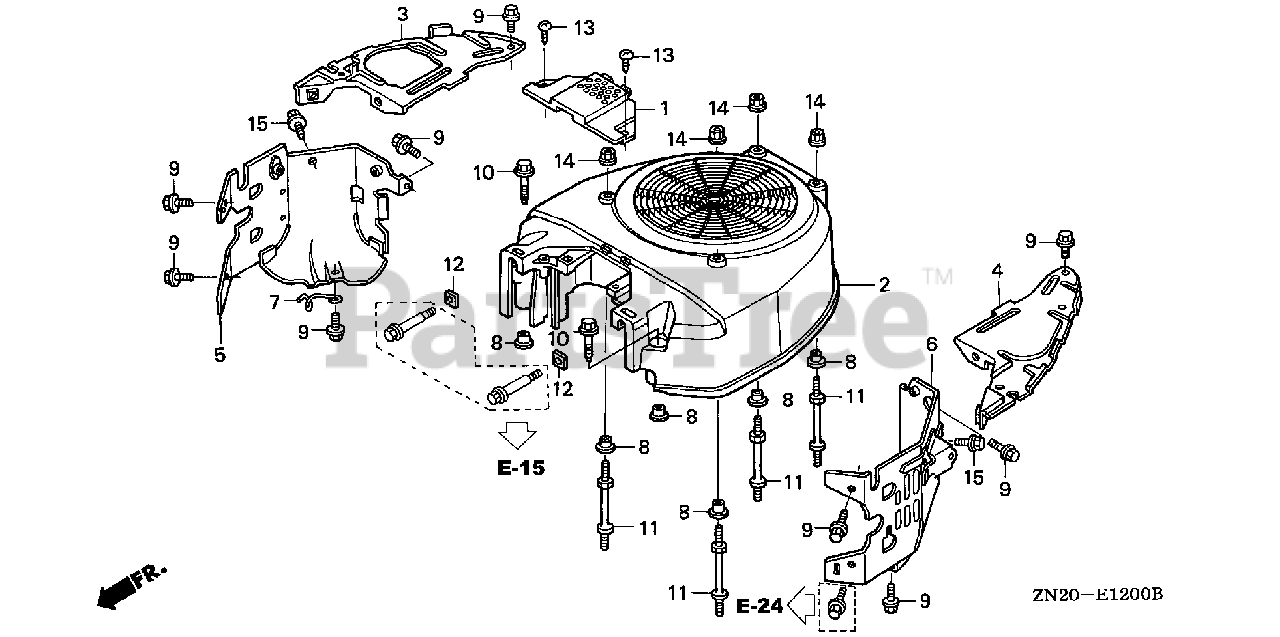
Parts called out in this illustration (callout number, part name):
1	COVER, FUEL PUMP
2	COVER, FAN *NH1* (BLACK)
2	COVER, FAN *R280* (POWER RED)
3	PLATE, SIDE
4	PLATE, SIDE
7	CLAMP, IGNITION TUBE
8	COLLAR B, TAILLIGHT
9	BOLT, FLANGE (6X12) (CT200)
10	BOLT, FLANGE (6X23) (CT200)
11	BOLT, STUD (6X71)
12	NUT, SQUARE (5MM)
13	SCREW, TAPPING (5X20)
14	NUT, FLANGE (6MM)
15	BOLT, FLANGE (6X8)
